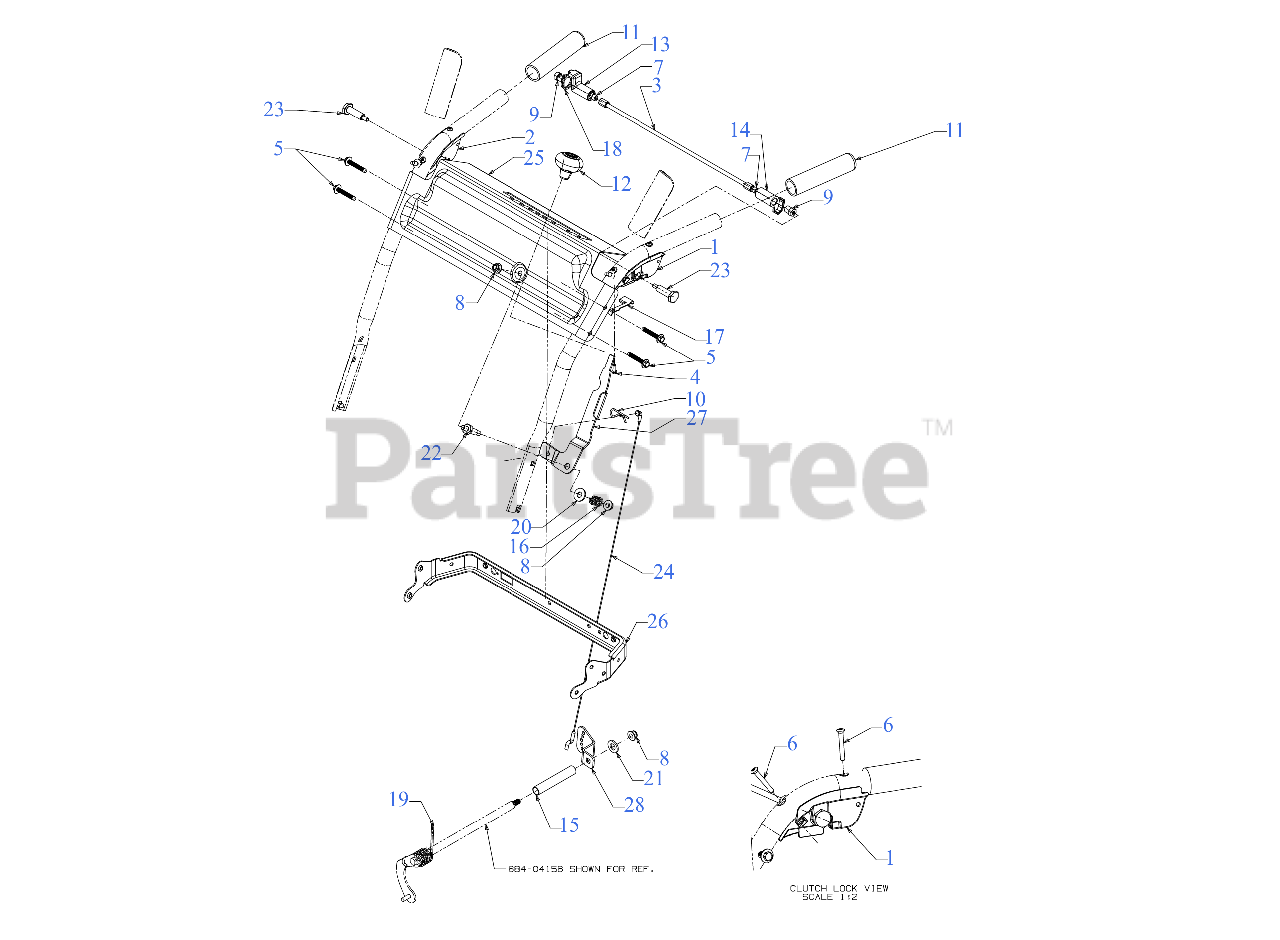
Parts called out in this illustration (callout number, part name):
1	CLUTCH LOCK HANDLE ASSEMBLY (LH)
2	CLUTCH LOCK HANDLE ASSEMBLY (RH)
3	PIVOT ROD
4	SCREW #8-16 x .50
5	SCREW 1/4-20 x 1.625
6	SCREW #10-24 x 1.375
7	SCREW 1/4-20 x .50
8	FLANGE LOCK NUT 5/16-18
9	HEX NUT W/PATCH
10	INTERNAL COTTER PIN
12	SHIFT KNOB
13	LOCK PLATE
14	CLUTCH LOCK CAM
15	COVER .505 X .635 X 3.64
16	COMPRESSION SPRING
17	CLUTCH SPRING
18	TORSION SPRING
19	TORSION SPRING
20	FLAT WASHER .385X.870X.090
21	FLAT WASHER
22	SHOULDER BOLT
23	SHOULDER SCREW .437 x 1.345 1/4-20
24	SPEED SELECTOR CABLE (STEEL)
25	HANDLE PANEL-STEEL (POWDER BLACK)
26	HANDLE SUPPORT BRACKET (POWDER BLACK)
27	SPEED SHIFT LEVER (POWDER BLACK)
28	SPEED SELECT SHIFT BRACKET
